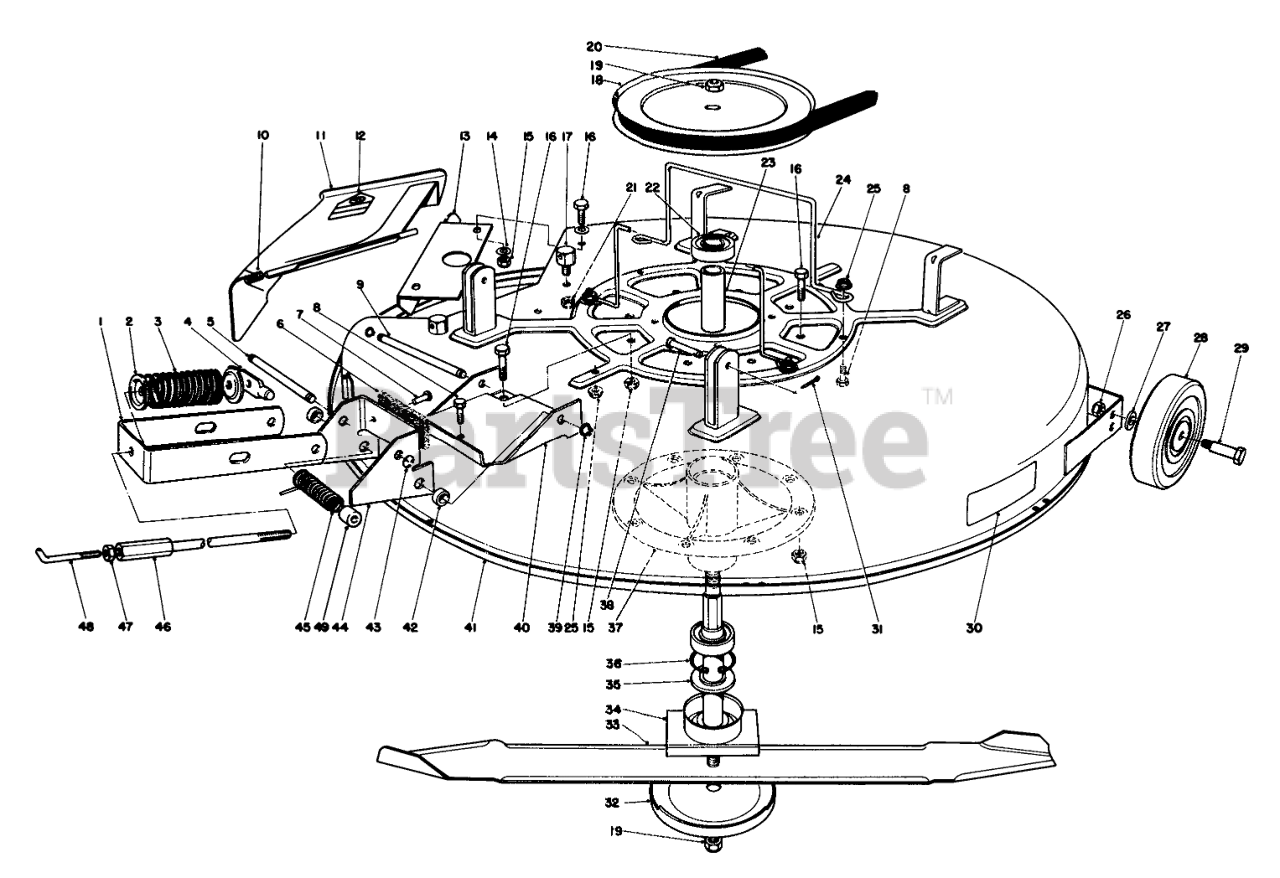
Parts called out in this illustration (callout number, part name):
1	Bracket-Engagement
2	RETAINER-SPR. TOP
3	SPRING-COMPRESSION
4	SHAFT-DECK ADJ.
5	Pin-Clevis
6	BRAKE PAD
7	RIVET .187 X 7/16 BRASS
8	SCREW-HH
9	CLEVIS PIN
10	SPRING
11	Deflector Assembly (Incl. Ref. #12)
12	DECAL-DANGER
13	Baffle Deck
14	WASHER-PLAIN
15	NUT-LOCK, NI
16	SCREW-HH
17	POST-PIVOT
18	PULLEY
20	V-BELT, DECK
21	NUT-LOCK, SIDE
22	BEARING-BALL
23	Spacer-Bearing
24	GUIDE-BELT
25	NUT-LOCK, HHF
26	NUT-LOCK, NI
27	WASHER-FLAT
28	WHEEL-DECK
29	BOLT-WHEEL
30	DECK DECAL
31	PIN-COTTER
32	Cup
33	Blade
34	SPINDLE SHAFT WA
35	SPACER-SPINDLE
36	RING-RETAINING
37	SPINDLE
38	PIN-CLEVIS
39	RING-RETAINING
40	DECK ENGAGE CHANNEL R
41	Cutter Deck
42	DECK BRAKE SPACER
43	E-RING
44	Support Deck Brake Assembly (Incl. Ref. #6 & 7)
45	SPRING
46	ADJ HUB WA
47	NUT-JAM
48	ADJ. ROD
49	CHAIN TENSION ROLLER
